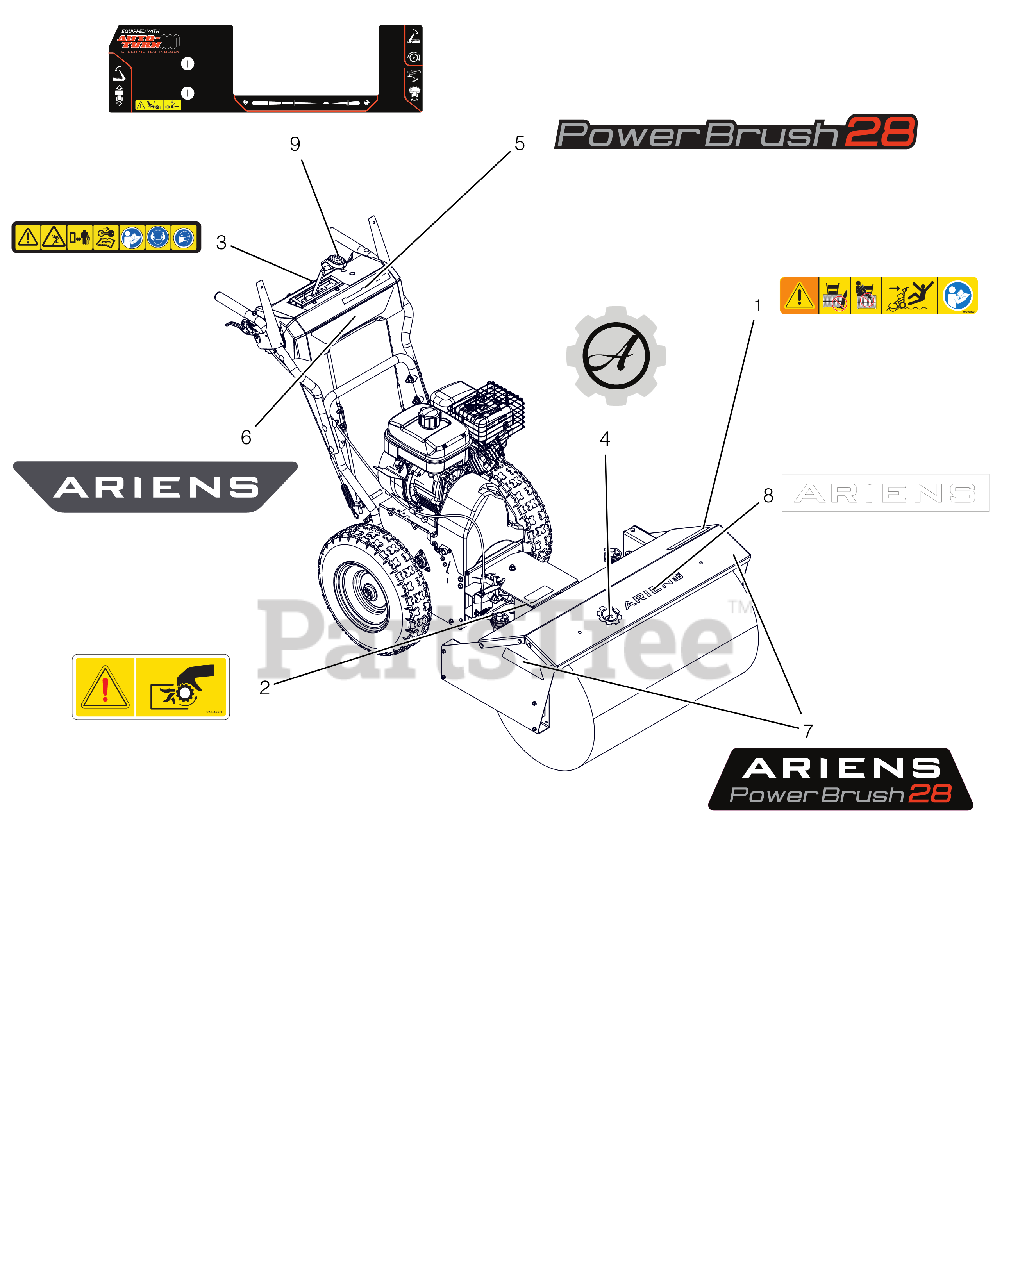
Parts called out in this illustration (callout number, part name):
1	DECAL, DANGER -POWER BRUSH-CE
2	DECAL, PTO WARNING
3	DECAL, SAFETY, DASH, BRUSH
4	DECAL, ARIENS-GEAR BADGE
5	DECAL, DASH - PB 28
6	DECAL, DASH BRAND - ARIENS PB
7	DECAL - ARIENS PB 28
8	DECAL - ARIENS 9.625"
9	DECAL, CONTROL-SMALL BRUSH
